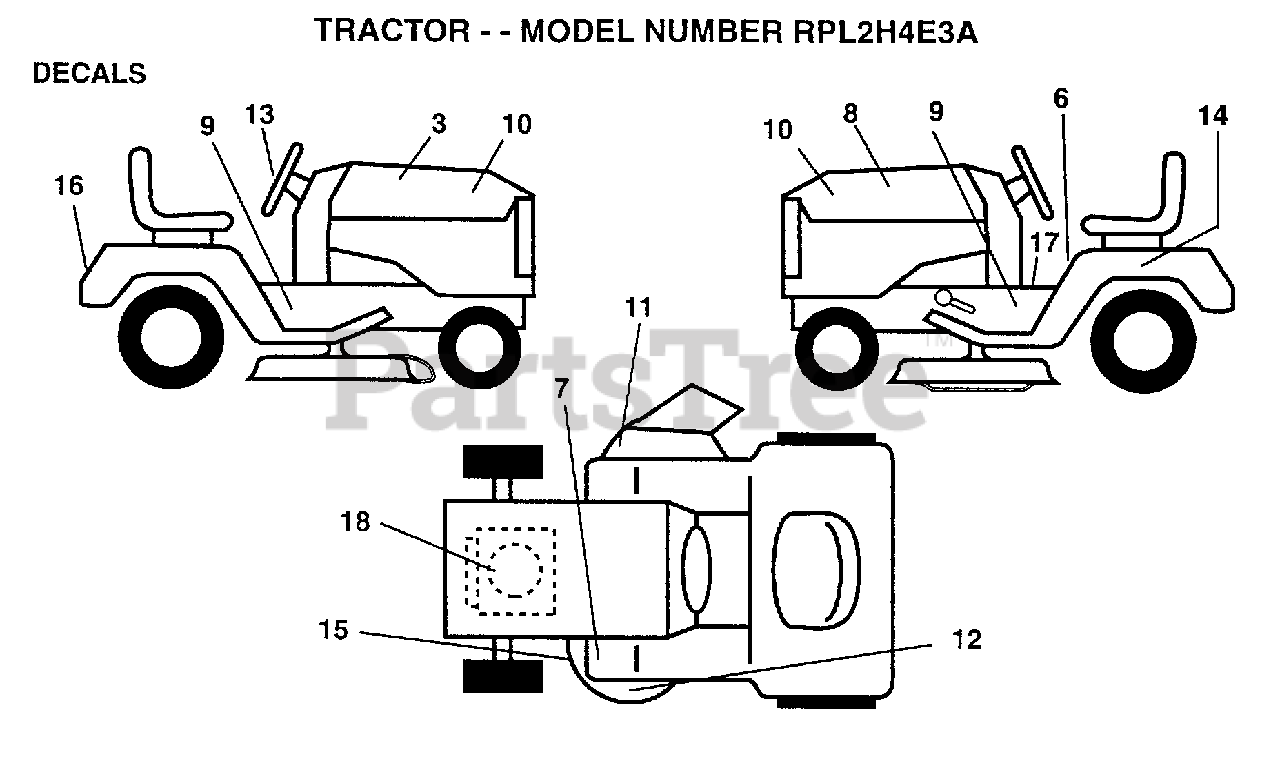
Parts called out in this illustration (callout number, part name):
3	DECAL HOOD RH
6	DECAL CAUTION
7	DECAL T
8	DECAL HOOD LH
9	CHASSIS DECAL
11	"DECAL, WARNING"
13	"DECAL,STR WHL"
14	DECAL.BTRY.DANGER
15	DECAL
16	FENDER DECAL
17	DECAL DASH INS OP
18	DECAL, HP ENGINE
